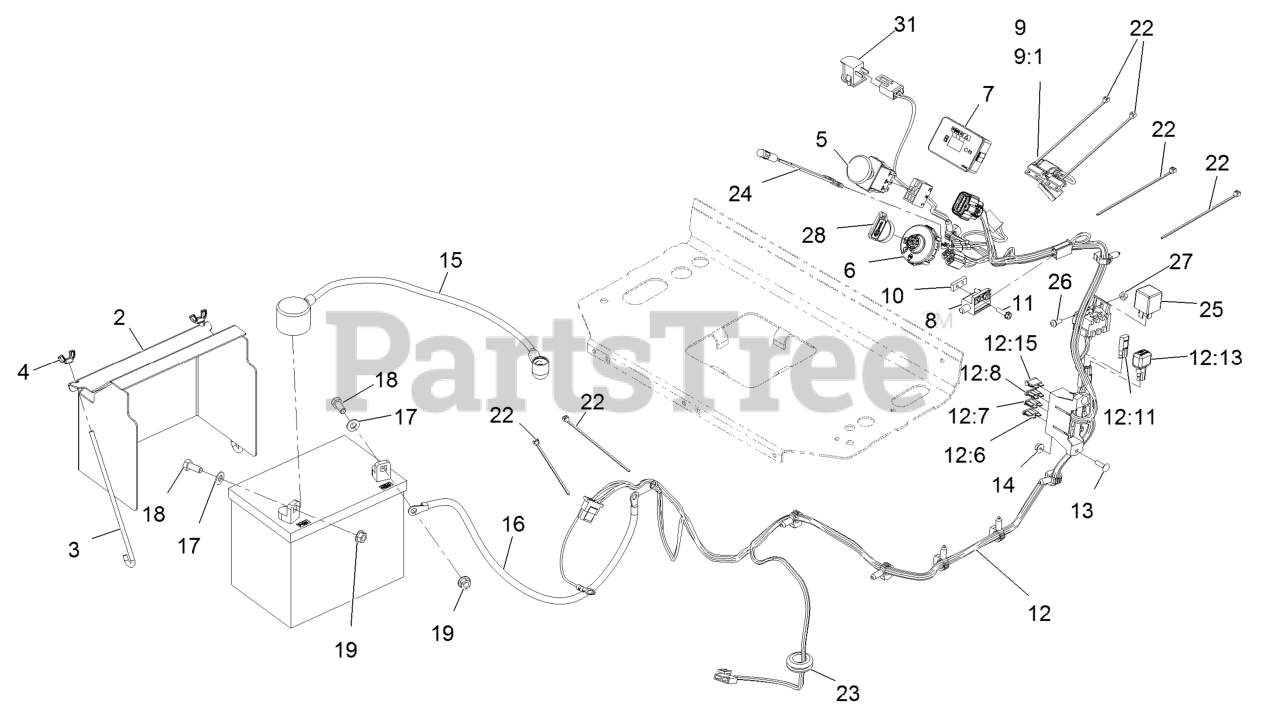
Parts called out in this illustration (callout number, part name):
2	Cover-Battery
3	Bolt-Holddown
4	Wingnut-Nyloc 1/4-20
5	Switch-PTO, On-On-(On)
6	Switch-Ignition
7	Module-Hour Meter
8	Switch-N.C.
9	Harness-Switch, Reed
9:1	Harness-Wire, Reed Switch
10	Plate-Tapped
11	Screw-HWH #10-24 X 3/4
12	Harness, Wire
12:6	Fuse-Blade, 30 Amp
12:7	Fuse-Blade, 25 Amp
12:8	Fuse-Blade, 10 Amp
12:11	Cap-Plug
12:15	Fuse-Blade, 15 Amp
13	Screw-CARR
14	Nut-Whizlock #10-24
15	Cable-Battery, Positive
16	Cable-Battery, Black
17	Washer-5/16 SAE
18	Screw-HH 5/16-18 X 3/4
19	Nut-Hex Flange 5/16-18
22	Tie-Cable 5 1/2 (Small)
23	Grommet
24	Indicator-Red LED
25	Relay-12Vdc 40 Amp
26	Screw-PPH #10-24 X 1/2
27	Nut-Nyloc #10-24
28	Key-Exmark Logo
